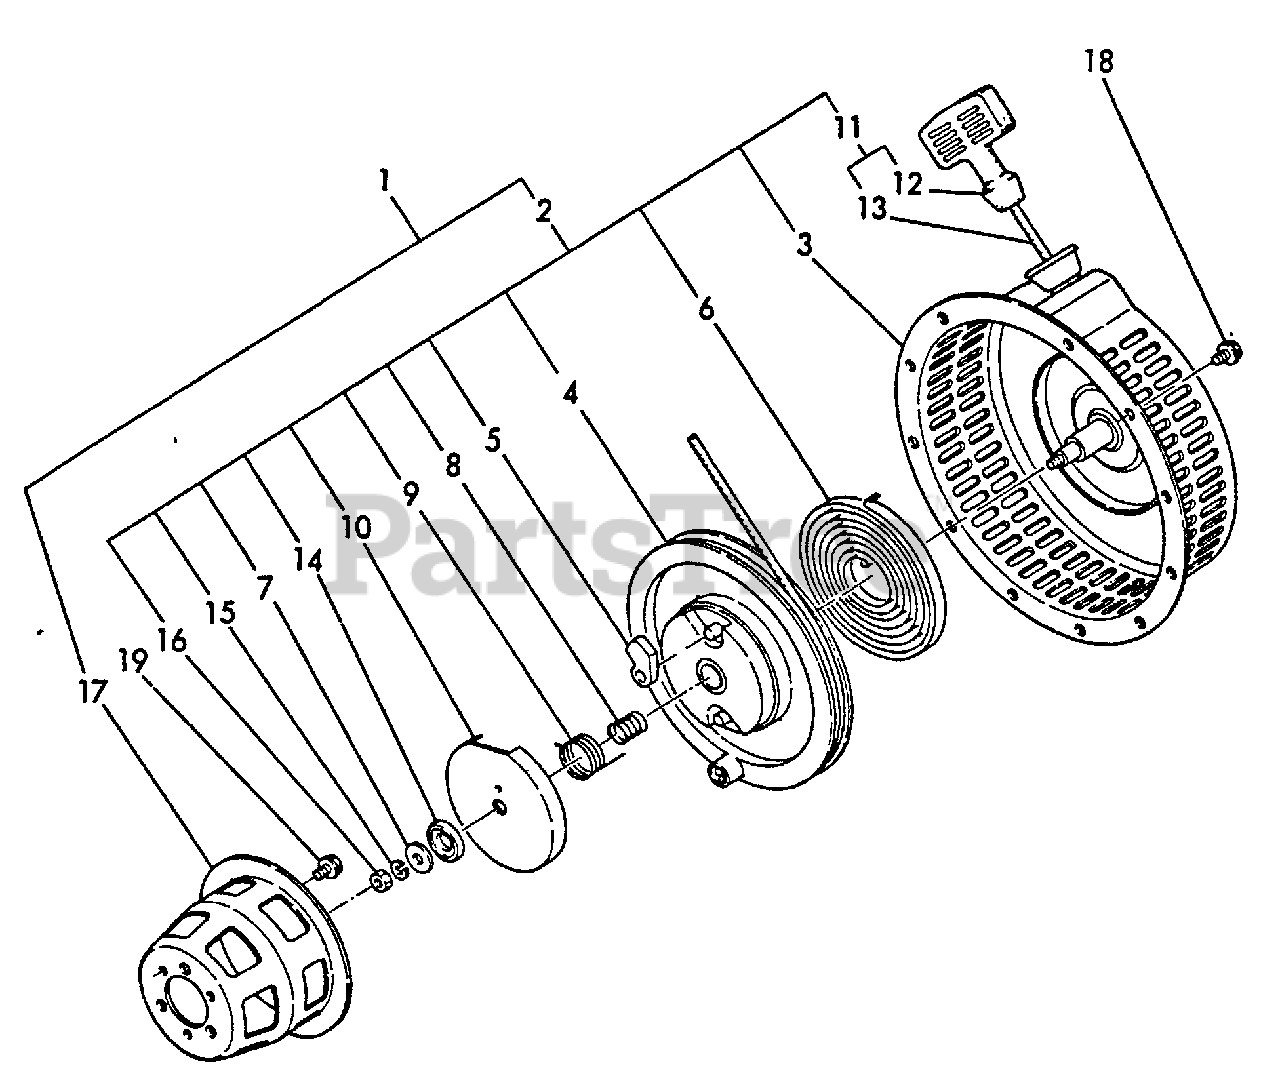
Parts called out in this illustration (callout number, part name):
1	STARTER ASSY
2	STARTER ASSY
3	CASE, STARTER
5	RATCHET
6	SPRING
7	WASHER, THRUST
8	SPRING, FRICTION
9	SPRING, RETURN
10	PLATE, FRICTION
11	STARTER ROPE ASSY
12	KNOB, STARTER
13	ROPE, STARTER
14	WASHER, THRUST
15	LOCKWASHER - 6
16	NUT - 6
17	REEL, ROPE
18	BOLT - 6X8 -- PLATED
19	BOLT - 6X12 -- PLATED
